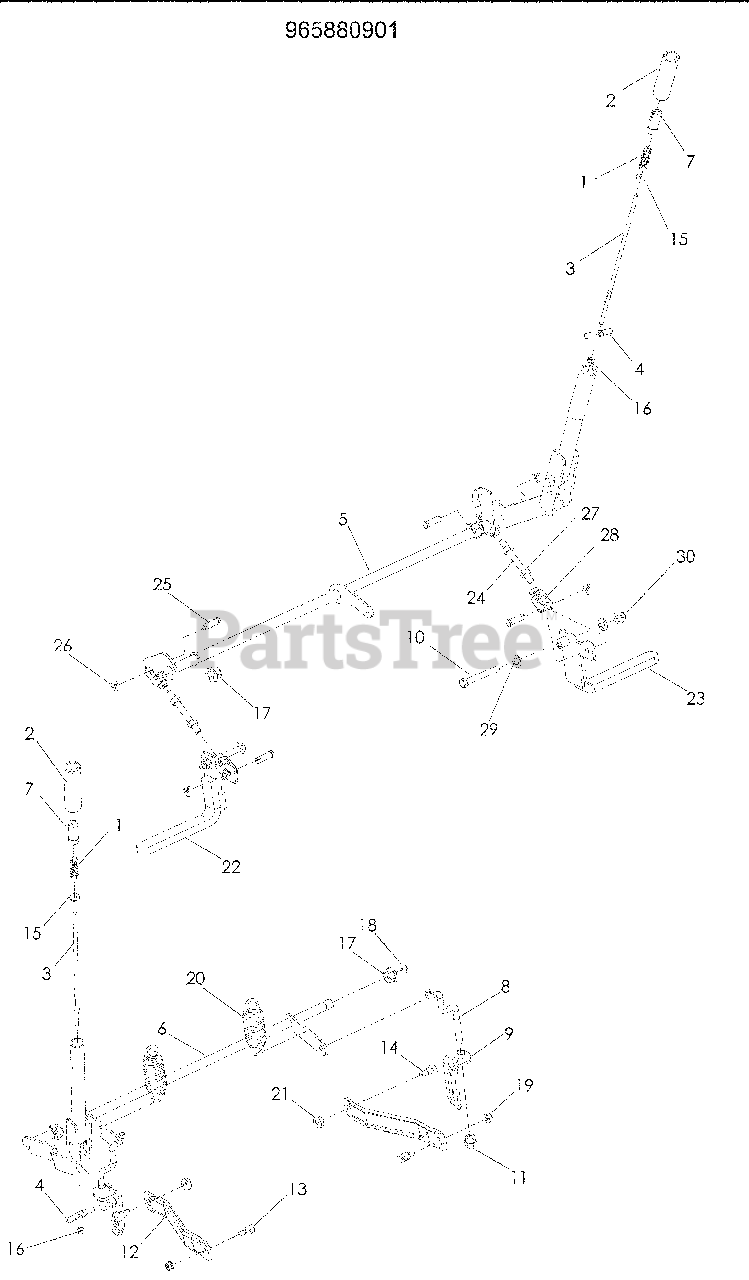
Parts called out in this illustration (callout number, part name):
1	SPRING, COMPRESSION
2	GRIP, HANDLE
3	ROD, HANDLE RELEASE
4	ROD, LATCH RELEASE
5	SHAFT, BRAKE
6	SHAFT, LIFT
7	BUTTON, PUSH
8	LINK, REAR SUSPENSION
9	BRACKET, CENTERING
10	HCS 3/8-16 x 3
11	NUT, LIFT LINK
12	ARM, SUSPENSION RR
13	STUD, w/ANTI- ROTATE
14	BOLT 3/8-16 x 3/8 SKT HD
15	WASHER ¼ FLAT
16	NUT ¼-20 HEX NYLOC
17	PLASTIC NUT
19	NUT 5/16-18 FLANGE NYLOC
24	ROD, THRD 3/8-24
25	CLEVIS PIN
26	PIN, COTTER 1/8 x ¾
27	NUT 3/8-24 HEX GR2
28	YOKE 3/8 SHORT
29	WASHER 3/8 SAE FLAT
30	NUT 3/8-16 HEX JAM NYLOC
